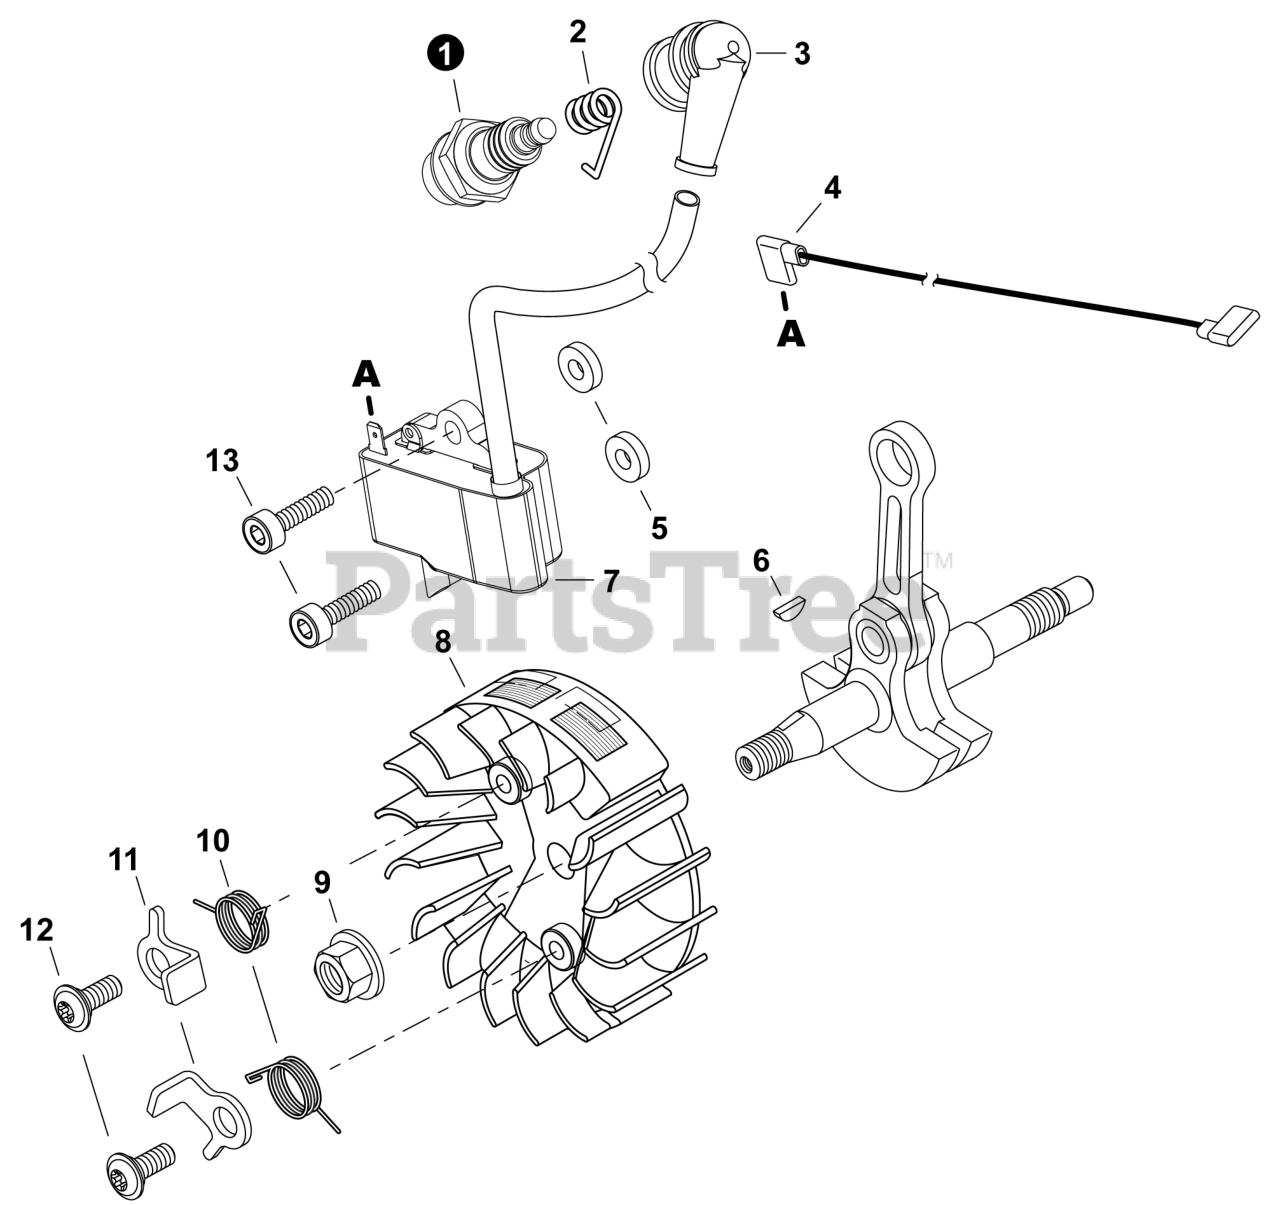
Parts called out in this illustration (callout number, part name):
1	SPARK PLUG - BPMR8Y
2	TERMINAL, SPARK PLUG
3	CAP, SPARK PLUG
5	WASHER 5.2x12x3
6	KEY, WOODRUFF
7	COIL, IGNITION
8	FLYWHEEL
9	NUT, FLANGE M8
10	SPRING, TORSION
12	BOLT 5x11
13	BOLT, TORX 5x20
